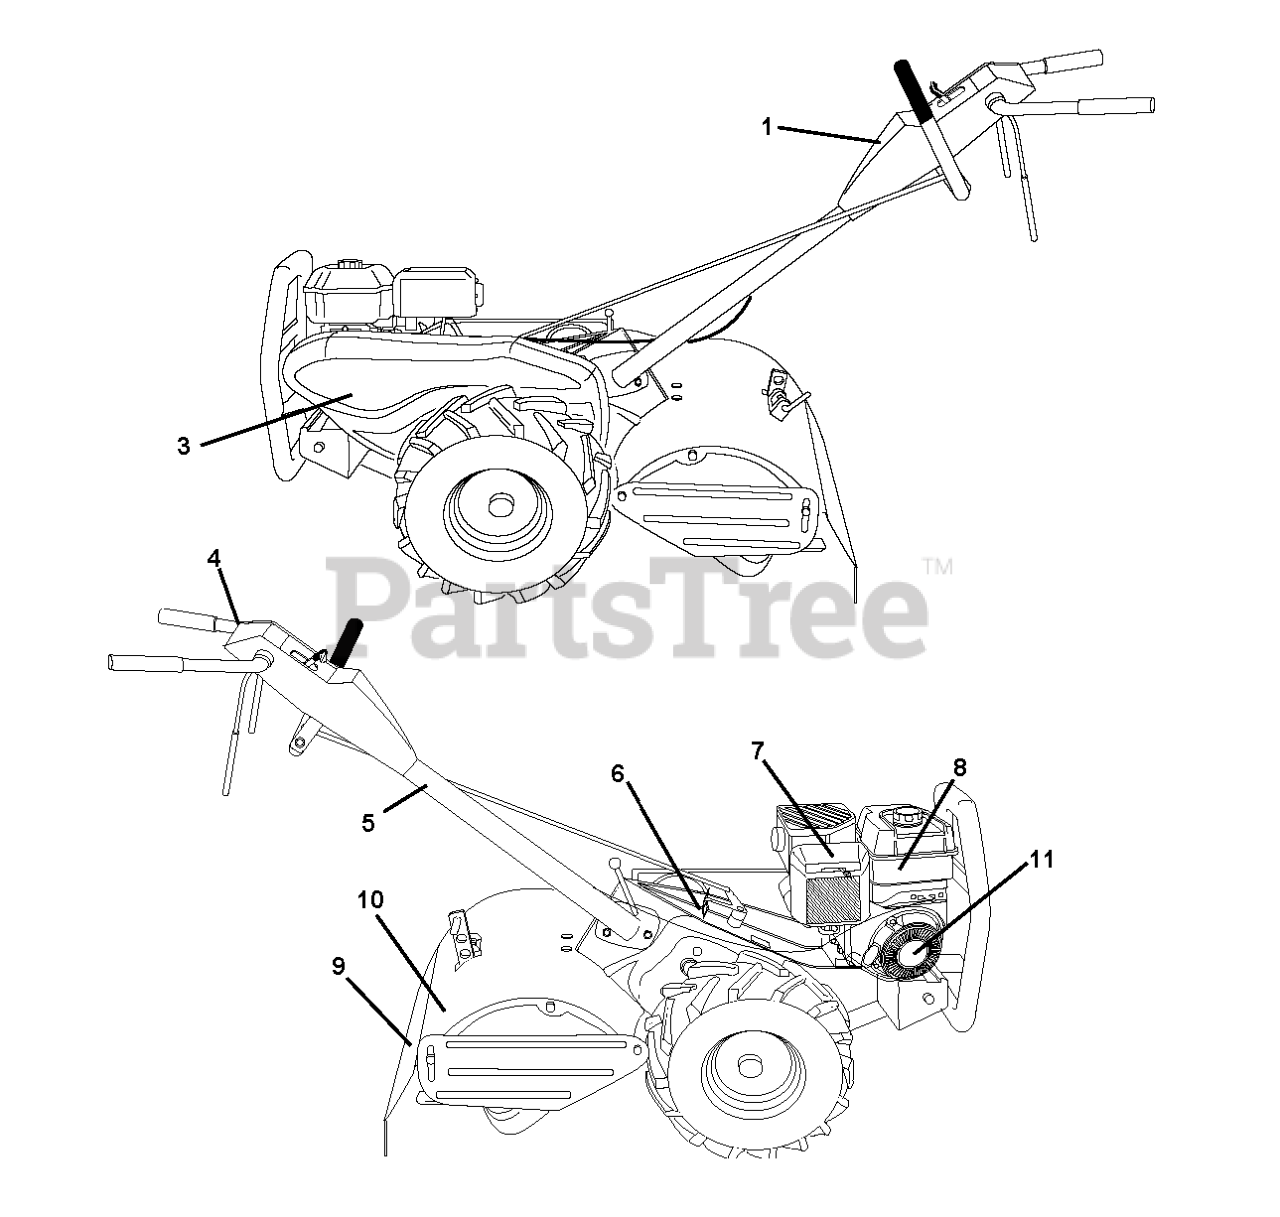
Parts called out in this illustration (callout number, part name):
3	DECAL.HOOD.LOGO.ORANGE.HUSQVAR
5	DECAL.PLACEMENT.HAND.SYMBOLS
6	DECAL.SHIFT.INDICATOR.TILLER
9	DECAL.WARNING.4-SYM.TILLER.INT
10	DECAL EUROPE STANDARD CE
11	DECAL, REWIND STARTER, B&S
